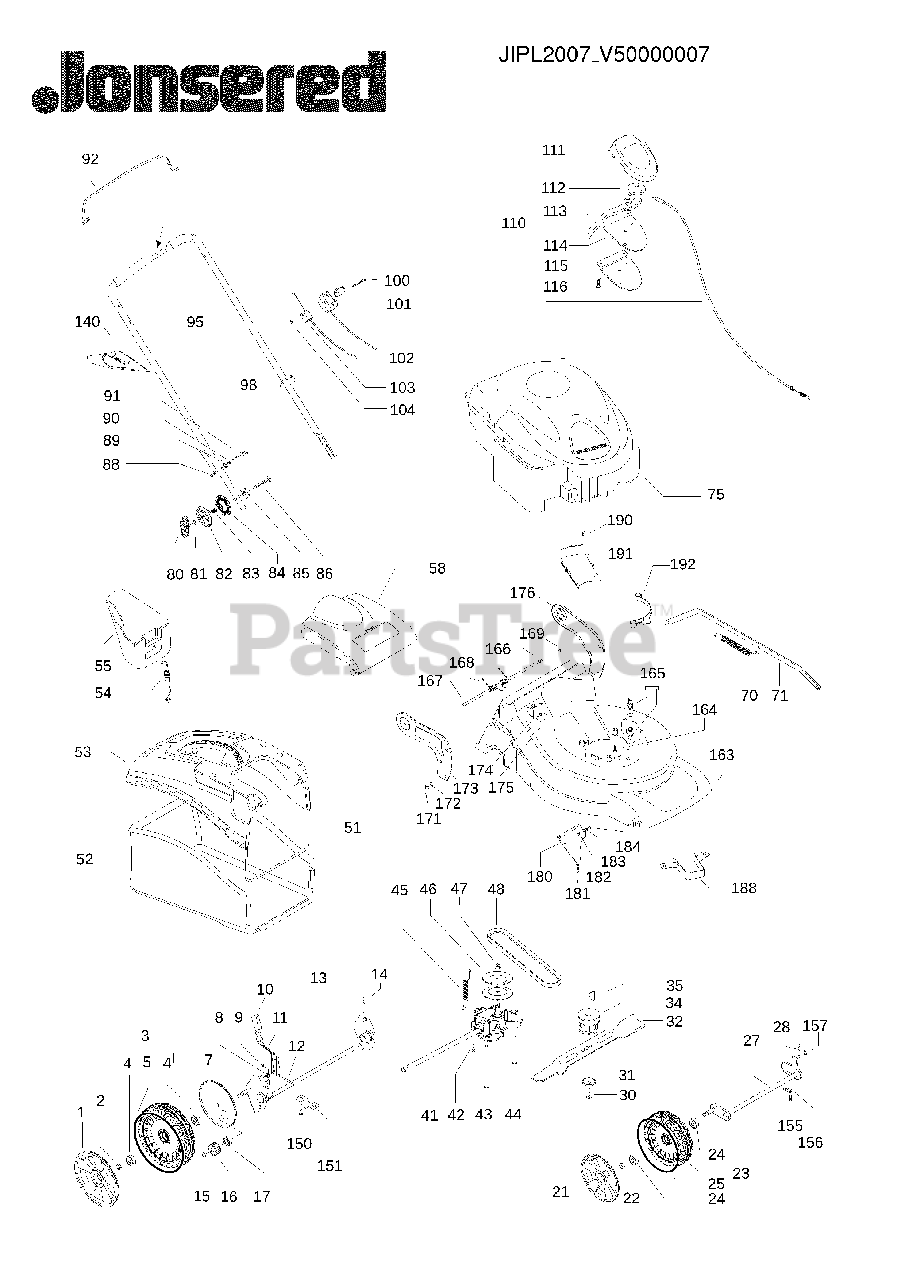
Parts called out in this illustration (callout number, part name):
111	CASE.TOP.GRAY
112	PULLEY, DRIVE CONTROL
113	LEVER
114	CASE BOTTOM
115	BRACKET, DRIVE CONTROL
116	SCREW, PHILLIPS HEAD 10 X 5/8
